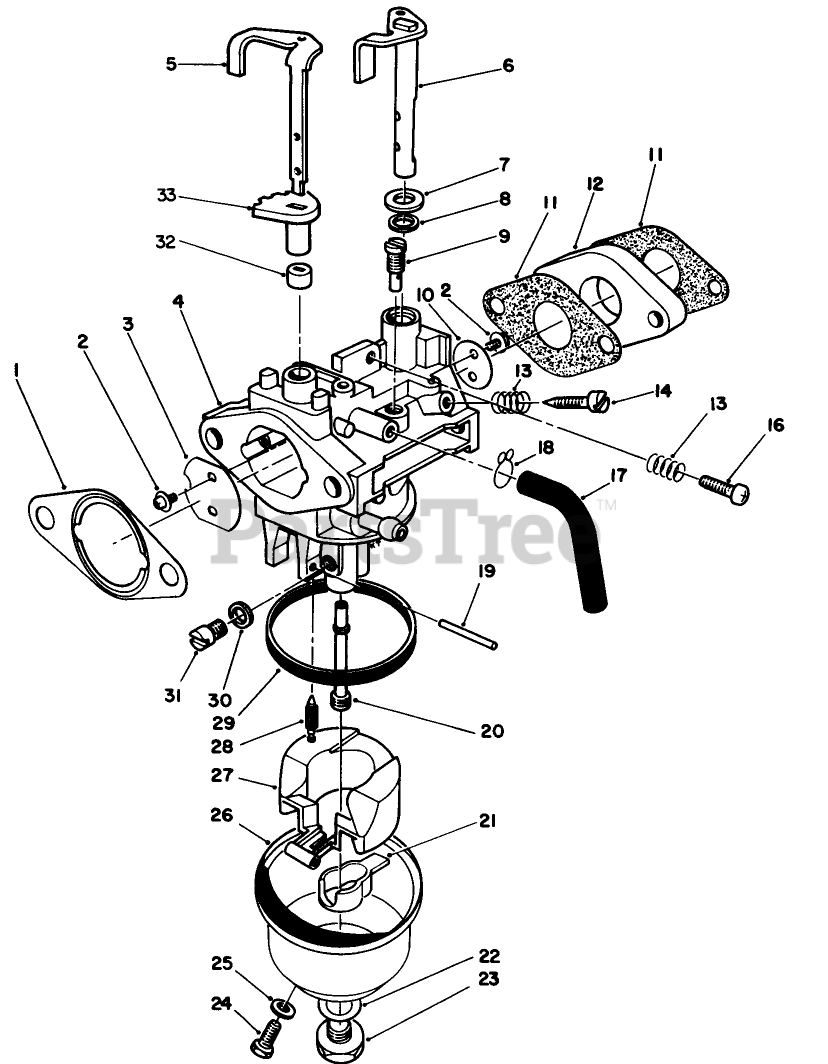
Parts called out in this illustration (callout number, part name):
1	GASKET F/W ENGINE
3	VALVE
4	Body-Carburetor
5	Shaft-Choke Valve
10	VALVE
11	GASKET INTAKE
13	SPRING-PILOT SCREW
14	ADJUSTER
16	SCREW
22	GASKET
23	SCREW
24	SCREW
25	GASKET
27	FLOAT
29	FLOAT BOWL GASKET
32	LOWER CHOKE RING
33	UPPER CHOKE RING
